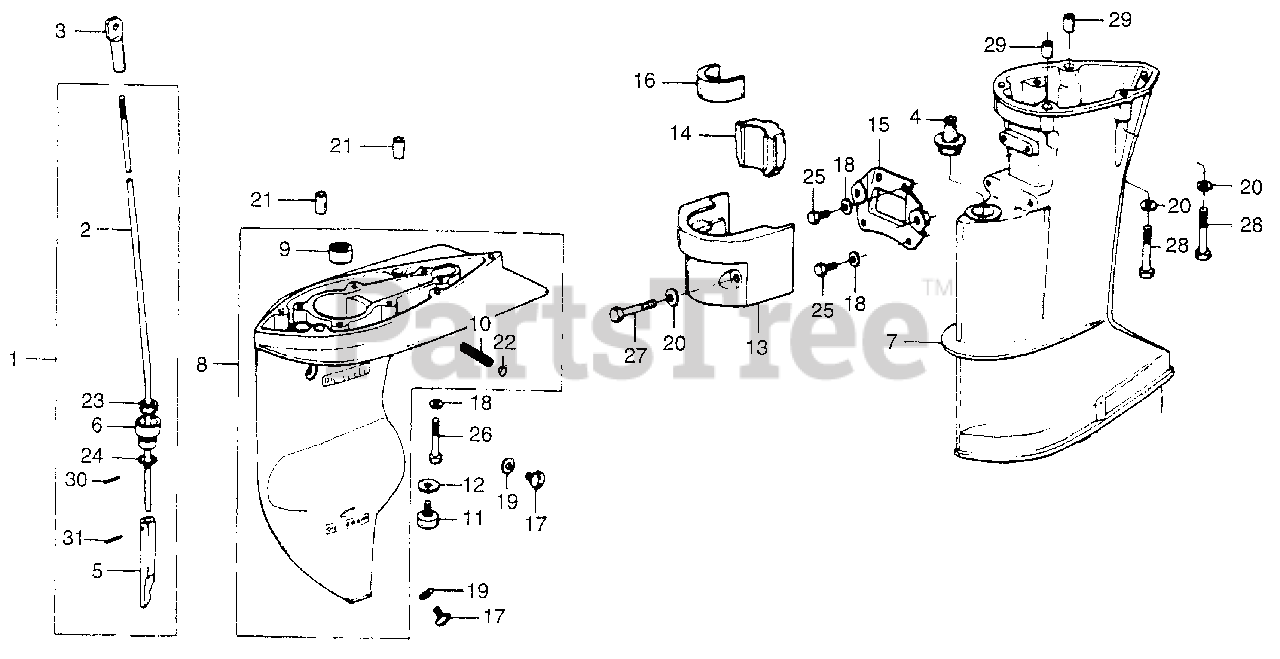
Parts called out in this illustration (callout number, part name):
1	ROD, GEARSHIFT (S)
2	ROD, GEARSHIFT (S)
3	JOINT, SHIFT ROD
4	GROMMET, ROD
5	ROD, PUSH
6	HOLDER, SEAL
7	CASE, EXTENSION *B9* (S) (ATLANTIS BLUE)
8	CASE, GEAR *B9* (ATLANTIS BLUE)
9	BEARING, NEEDLE (15X21X16)
10	SCREEN, WATER
11	METAL, ANODE
13	HOUSING, SETTING (LOWER) *B9* (ATLANTIS BLUE) (NOT AVAILABLE)
14	RUBBER A, MOUNTING (LOWER)
15	PLATE, SETTING (LOWER)
16	RUBBER B, SETTING (LOWER)
17	BOLT, OIL CHECK
18	WASHER, PLAIN (6MM)
19	WASHER, NYLON (8MM)
20	WASHER, PLAIN (8MM)
21	PIN, DOWEL (8X10)
22	PLUG, SEALING (10MM)
23	SEAL, WATER (6MM)
24	O-RING (13.8X2.5)
25	BOLT, HEX. (6X12)
26	BOLT, HEX. (6X40)
27	BOLT, HEX. (8X40)
28	BOLT, HEX. (8X50)
29	PIN A, DOWEL (10X14)
30	PIN, SPRING (2.5X12)
31	ROLLER (2.5X11.8)
